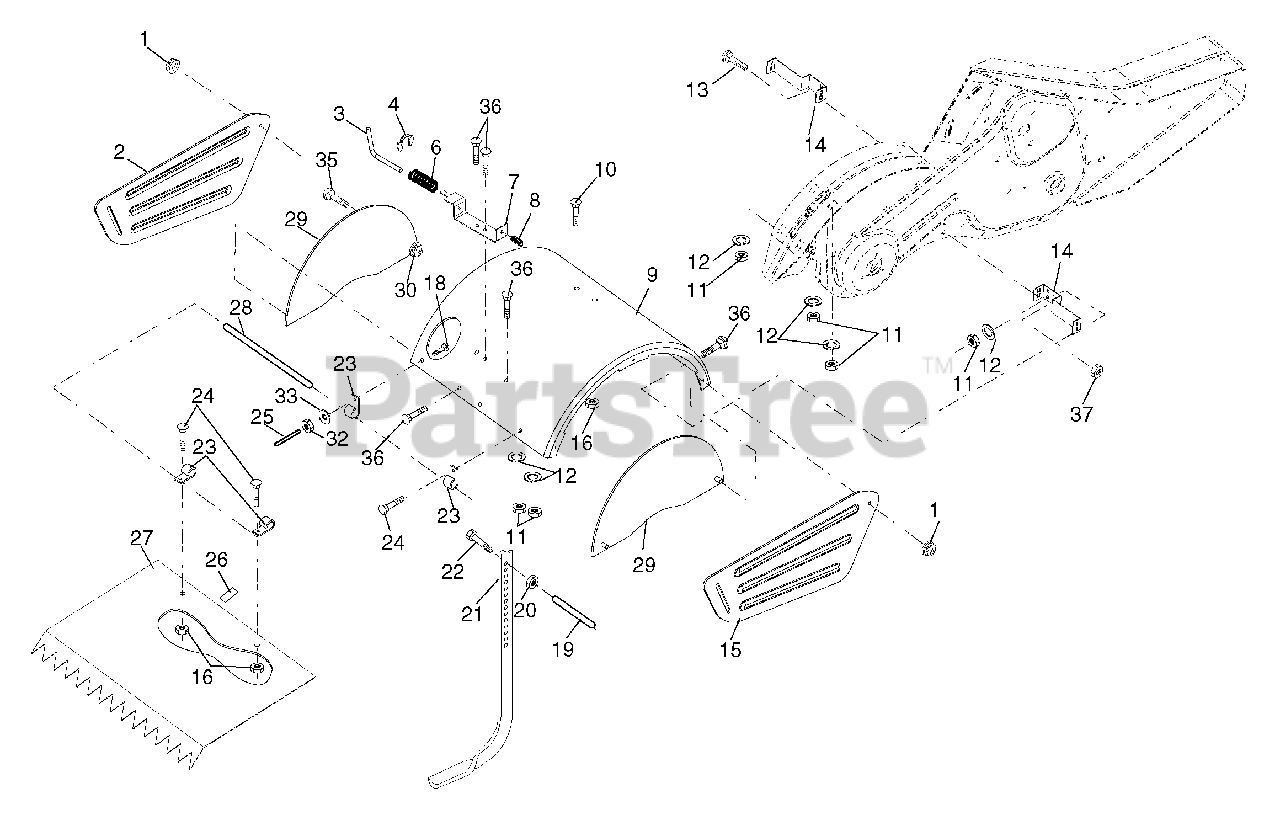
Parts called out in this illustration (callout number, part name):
1	Nut, Hex, Flangelock 5/16-18
2	Shield, Side, Outer, LH
3	Pin, Stake, Depth
4	Ring, Klip
5	Bolt, Carriage 5/16-18 x 3/4
7	Bracket, Latch
8	Spring, Depth Stake
9	Shield, Tine
10	Bolt, Carriage 5/16-18 x 1
11	Nut, Hex 5/16-18
12	Washer, Lock 5/16
13	Bolt, Carriage 5/16-18 x 1-1/4
14	Bracket, Shield, Tine
15	Shield, Side, Outer, RH
16	Nut, Hex Flange 1/4-20
18	Bolt, Carriage 1/4-20 x 1-1/4
20	Nut, Hex 3/8-16
21	Stake, Depth
22	Bolt, Hex Head 3/8-16 x 2
24	Bolt, Carriage, Grade 5 1/4-20 x 1/2
25	Cap, Vinyl
26	Pad, Idler
27	Shield, Leveling
28	Pin, Hinge
29	Shield, Side
30	Nut, Hex, Flangelock
32	Nut, Hex 1/4-20
33	Washer, Lock, Heavy Helical 1/4
34	Locknut, Hex 5/16-18
35	Bolt, Carriage 5/16-18 x 5/8
